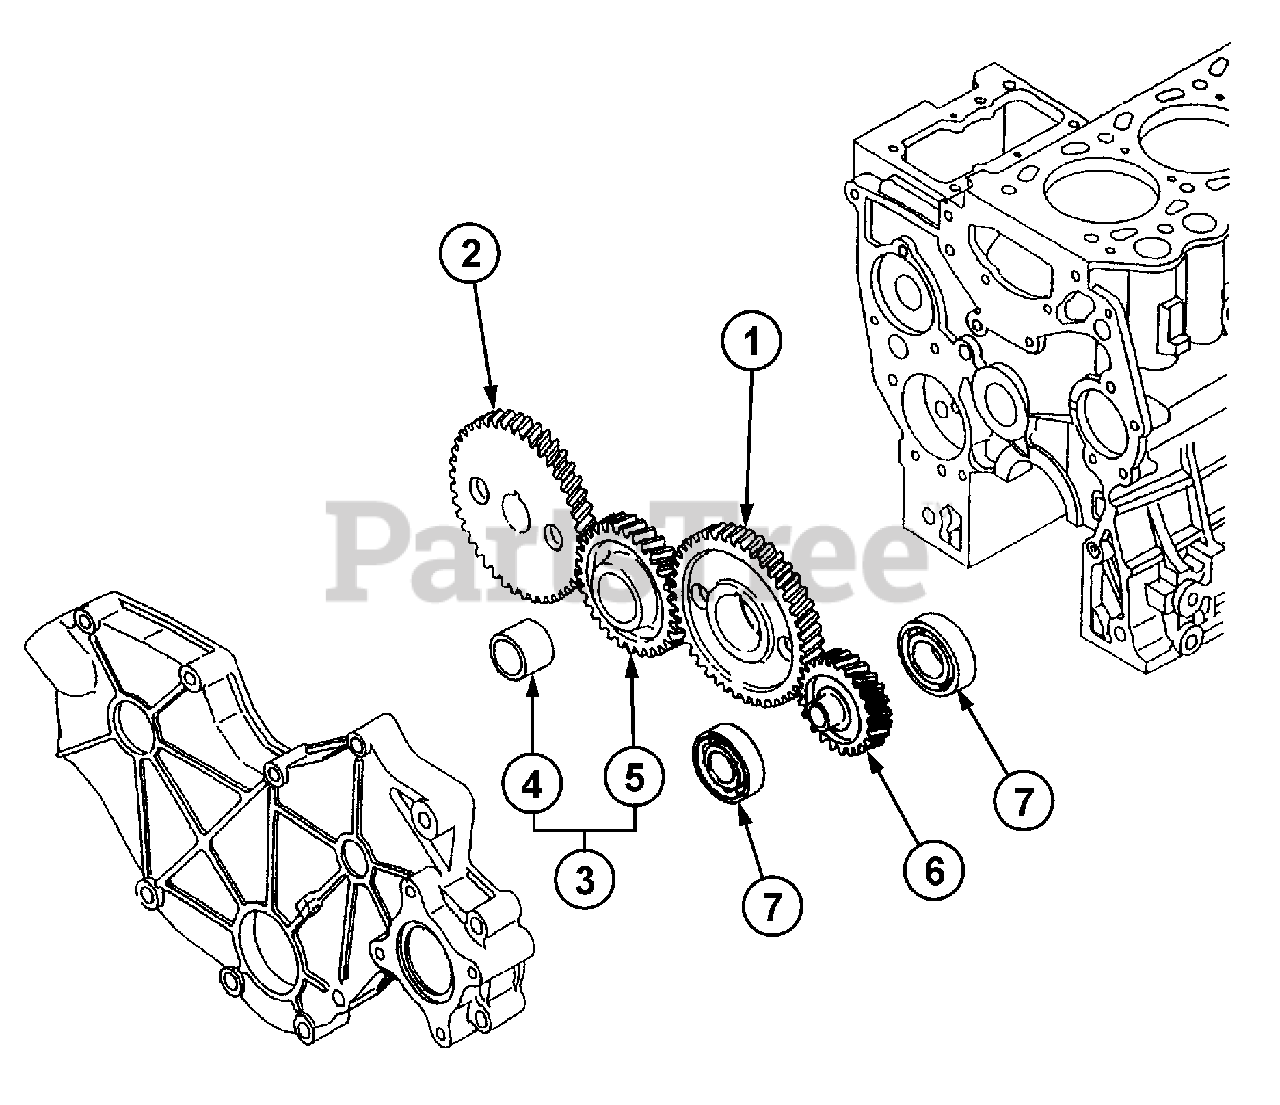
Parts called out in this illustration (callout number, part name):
1	Gear, Camshaft
2	Gear, Inj. Pump
3	Gear Assy, Idler
4	Bushing, Idler
5	Gear, Idler
6	Gear, Oil Pump
